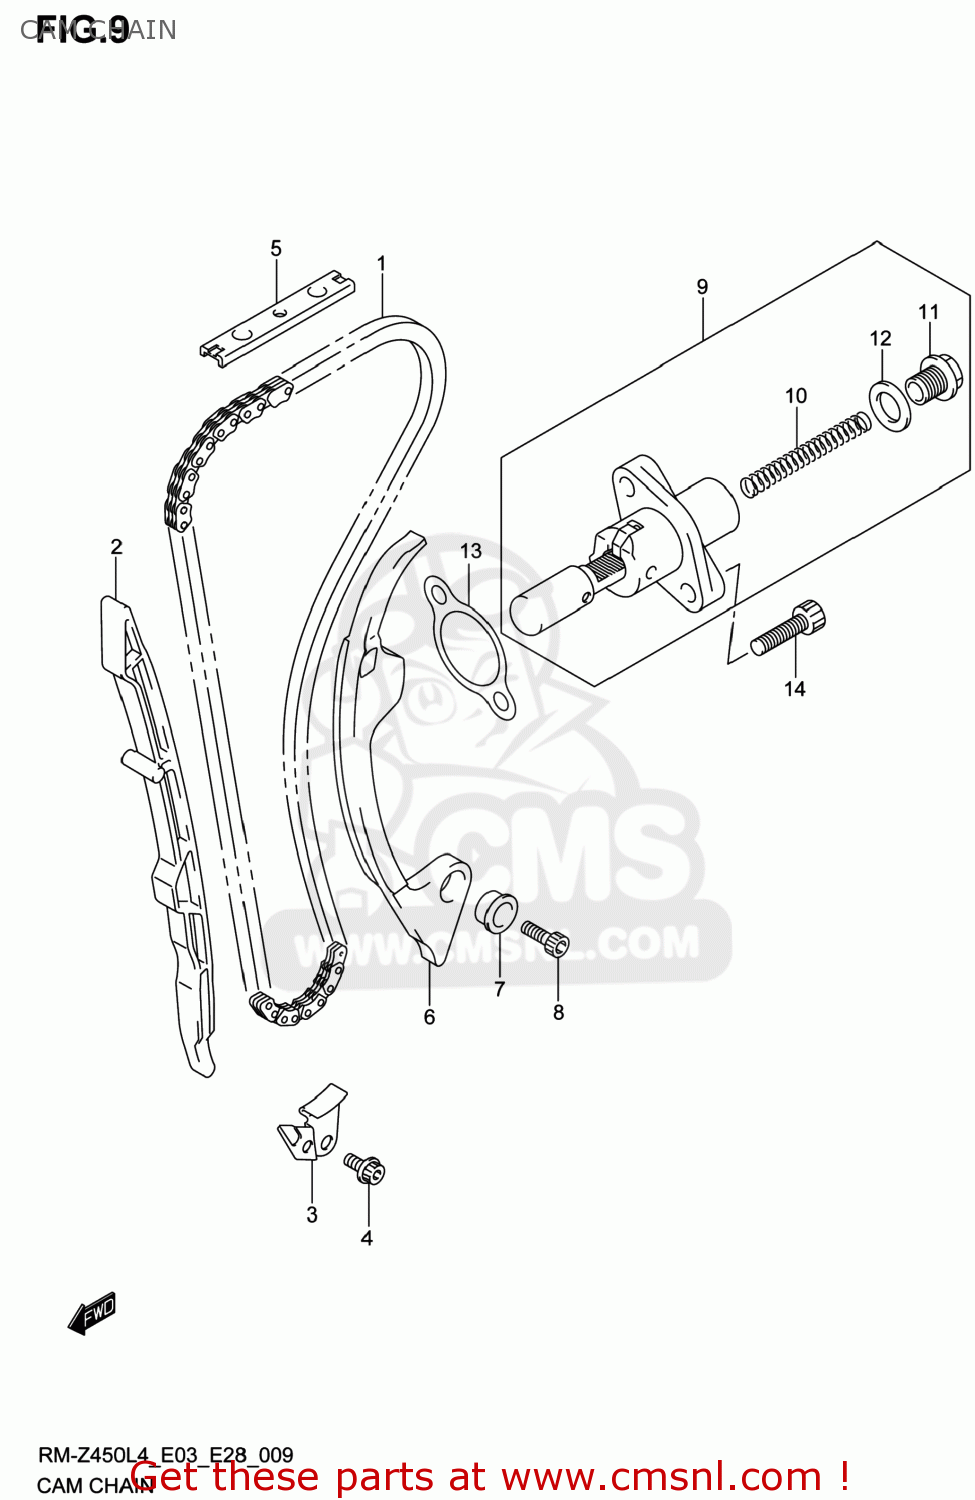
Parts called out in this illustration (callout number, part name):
1	CHAIN,CAMSHAFT DRIVE
2	GUIDE,CAM CHAIN NO.1
3	RETAINER,CAM CHAIN GUIDE NO.1
4	BOLT
5	GUIDE,CAM CHAIN NO.2
6	TENSIONER,CAM CHAIN
7	SPACER,CAM CHAIN TENSIONER
8	BOLT
9	ADJUSTER ASSY,TENSIONER
10	SPRING
11	PLUG,FR TENSIONER ADJ
12	GASKET,TENSIONER ADJUSTER (NAS)
13	GASKET,TENSIONER ADJUSTER (NAS)
14	BOLT
